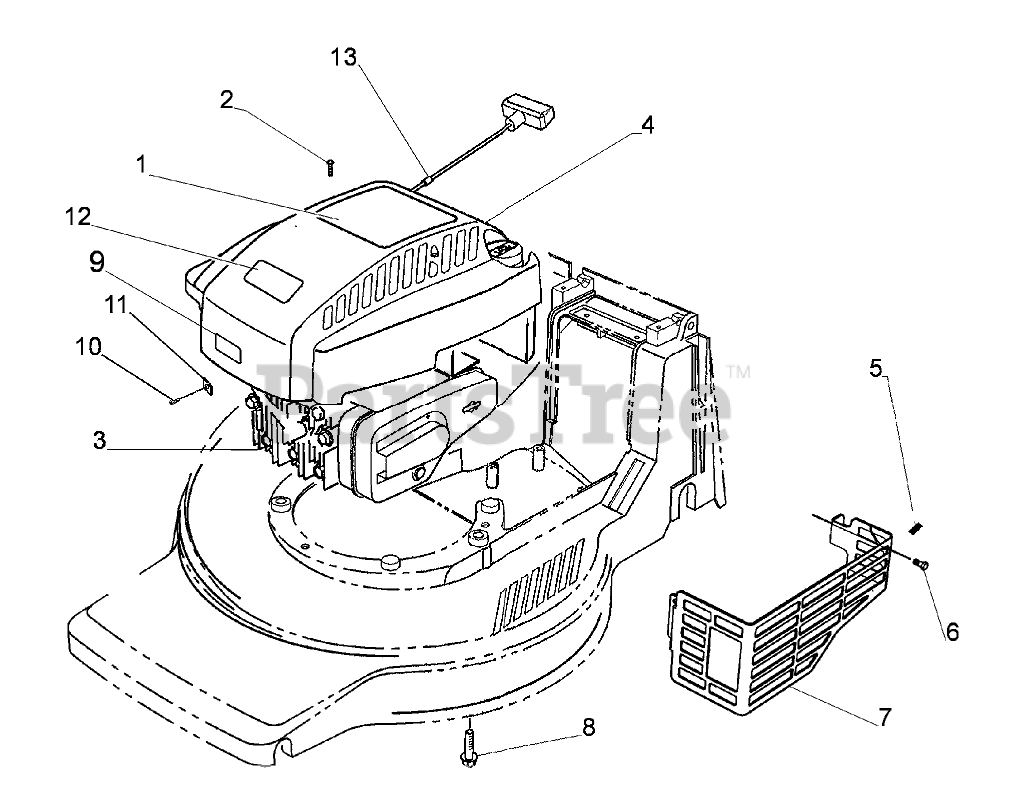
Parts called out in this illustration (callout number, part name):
1	Decal-Shroud
2	SCREW-PPH
4	SHROUD-ENGINE
5	TIE-CABLE
6	SCREW-HWH
7	SHIELD-MUFFLER
8	SCREW-HWH
9	PLATE-LOGO
10	SCREW-CLAMP
11	CLAMP-CASING
12	PLATE-LOGO
13	STOP-ROPE
